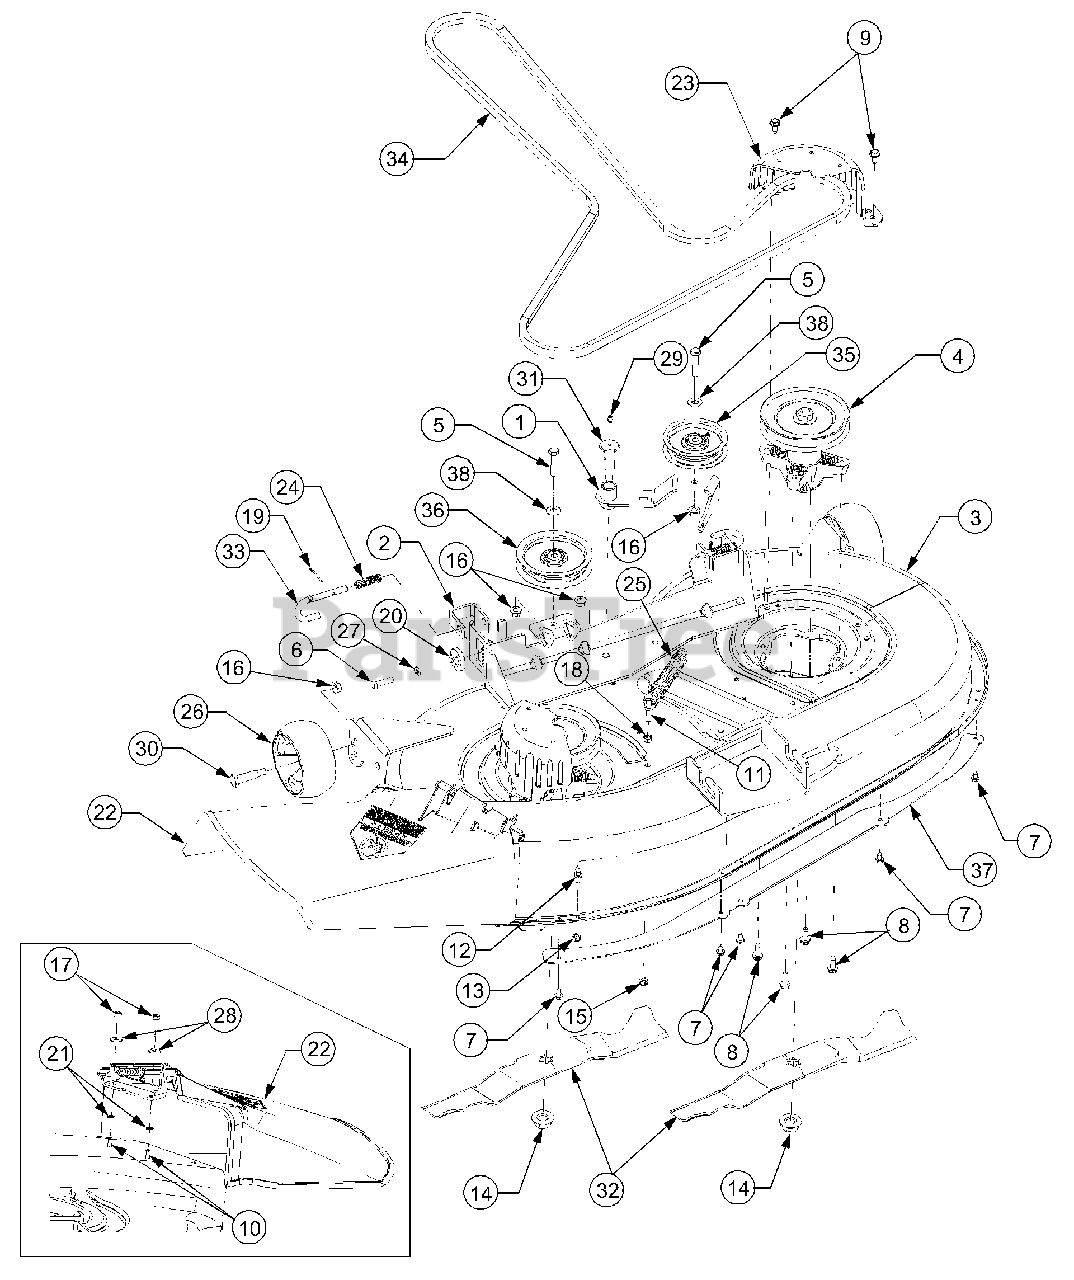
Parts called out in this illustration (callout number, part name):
4	Spindle Assembly
5	Screw, Hex Cap, 3/8-16 x 1.75 GR5
6	Screw, Hex Cap, 5/16-18 x 1.25 GR5
7	Screw, Hex Wash. Hd. Tapp 1/4-20 x .5
8	Screw, Hex Wash. Hd. Tapp 5/16-18 x .875
9	Screw, Hex Wash. Hd. Tapp 5/16-12 x .75
10	Screw, Hex Cap, 1/4-20 x .62 GR5
11	Screw, Hex Cap, 5/16-18 x 1.75 GR5
12	Pin, Grass Catcher, 1/4-20
13	Nut, Hex Insert Lock, 1/4-20 GR8
14	Nut, Hex Flange, 5/8-18
15	Nut, Hex Insert Lock, 5/16-18 GR5
16	Nut, Hex Flange, 3/8-16 GRF
17	Nut, Hex, 1/4-20 GR5
18	Nut, Hex, 5/16-18 GR5
19	Pin, Cotter, 1/8 x 1.25
20	Gear, Deck Adjustment
21	Nut, Push, .25 x .5
22	Chute Assembly, Discharge
24	Spring, Compression
25	Spring, Extension, .94 Dia. x 6.74
26	Wheel, Deck Ball, 5.0
27	Washer, Lock, 5/16
28	Washer, Bell, .265 x .75 x .062
29	Fitting, Lube, 3/16 Drive
30	Screw, Shoulder, .498 x 1.53:3/8-16
31	Screw, Shoulder, .68 x 1.59
32	Blade, Hi-Lift, 21.23
33	Rod, Deck Hanger
34	Belt, V, Type A Sec x 109
35	Pulley, Idler, 3.5 Dia.
36	Pulley, Idler, 4.06 Dia
38	Washer, Flat, .38 x .93 x .11 HT
